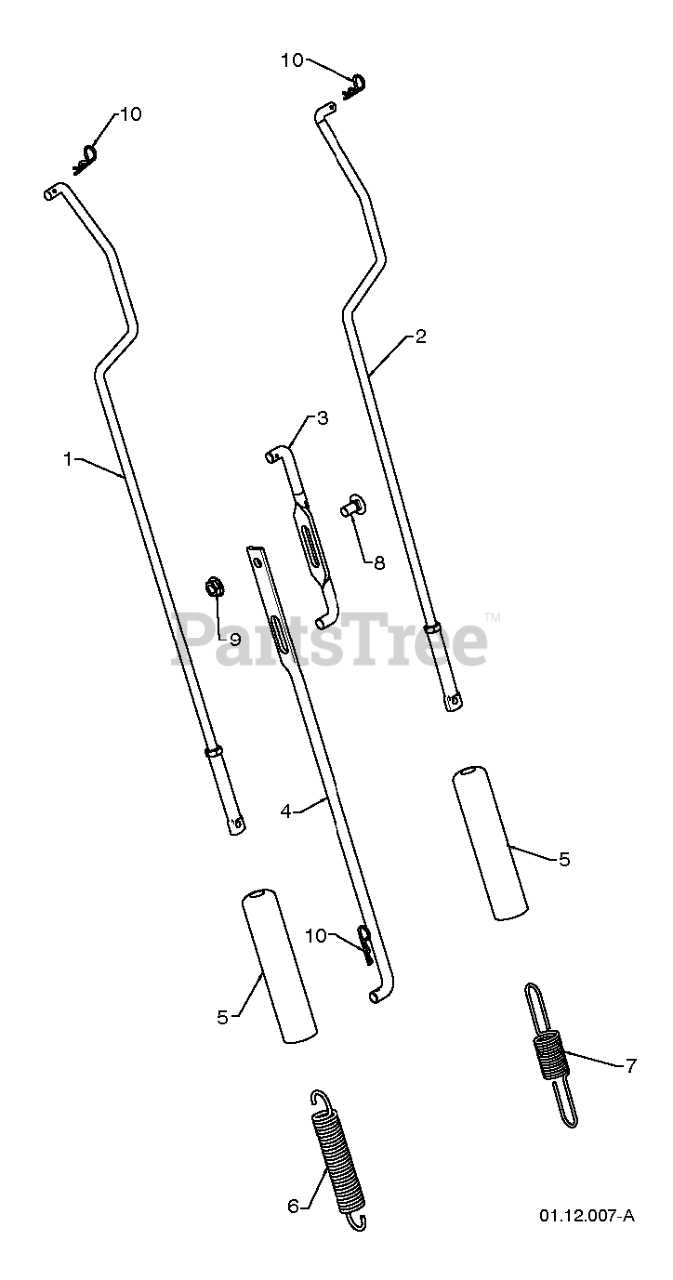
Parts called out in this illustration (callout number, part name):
1	ROD.ASM.IMPELLER
2	ROD.ASM.TRACTION.HYD.CLUTCH
3	ROD.SHIFTER.TOP.HYD
4	ROD, LOWER, SPEED CONTROL
5	SLEEVE, SPRING
6	SPRING, AUGER CONTROL
7	SPRING, TRACTION DRIVE
8	BOLT
9	NUT.FLANGE.5/16
10	SPRING RETAINER
